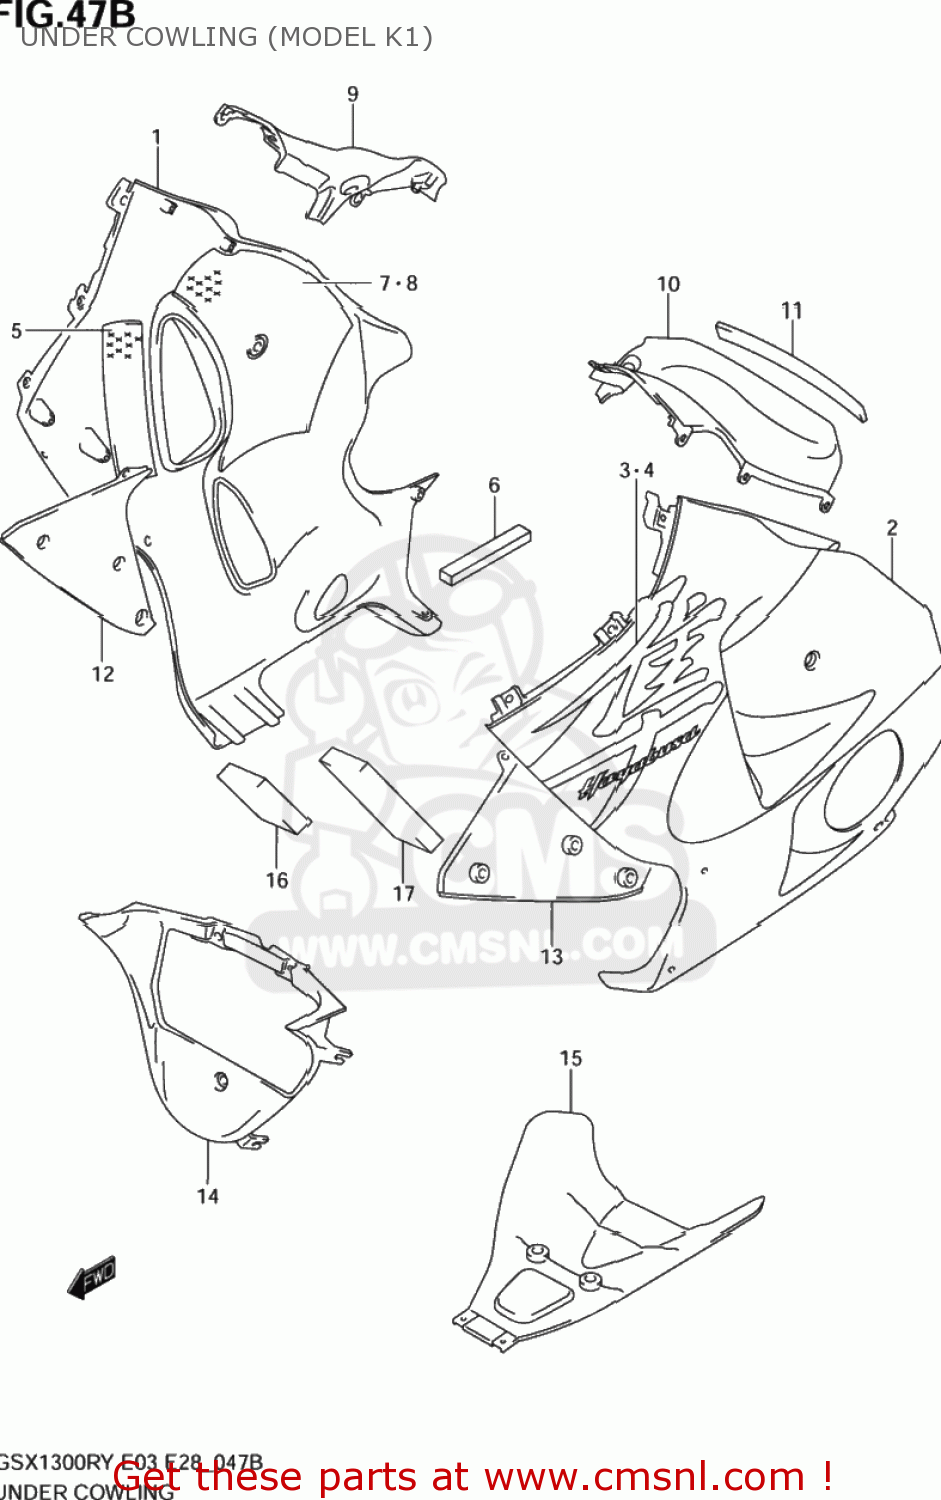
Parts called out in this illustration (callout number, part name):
1	COWLING ASSY,U
2	COWLING ASSY,U
3	EMBLEM,COWLING UNDER,R
4	EMBLEM,COWLING UNDER,L
5	CUSHION,UNDER COWLING NO,1
6	CUSHION,ENGINE COVER,RIGHT
7	CUSHION,UNDER COWLING NO.2,R
8	CUSHION,UNDER COWLING,L
9	PANEL,SIDE,R
10	PANEL,SIDE,L
11	MOLDING,SIDE PANEL
12	COWLING,UNDER INNER,R
13	COWLING,UNDER INNER,L
14	COWLING,UNDER CTR
15	COWLING,UNDER RR
16	CUSHION,UNDER COWLING,RIGHT
17	CUSHION,UNDER COWLING,L
